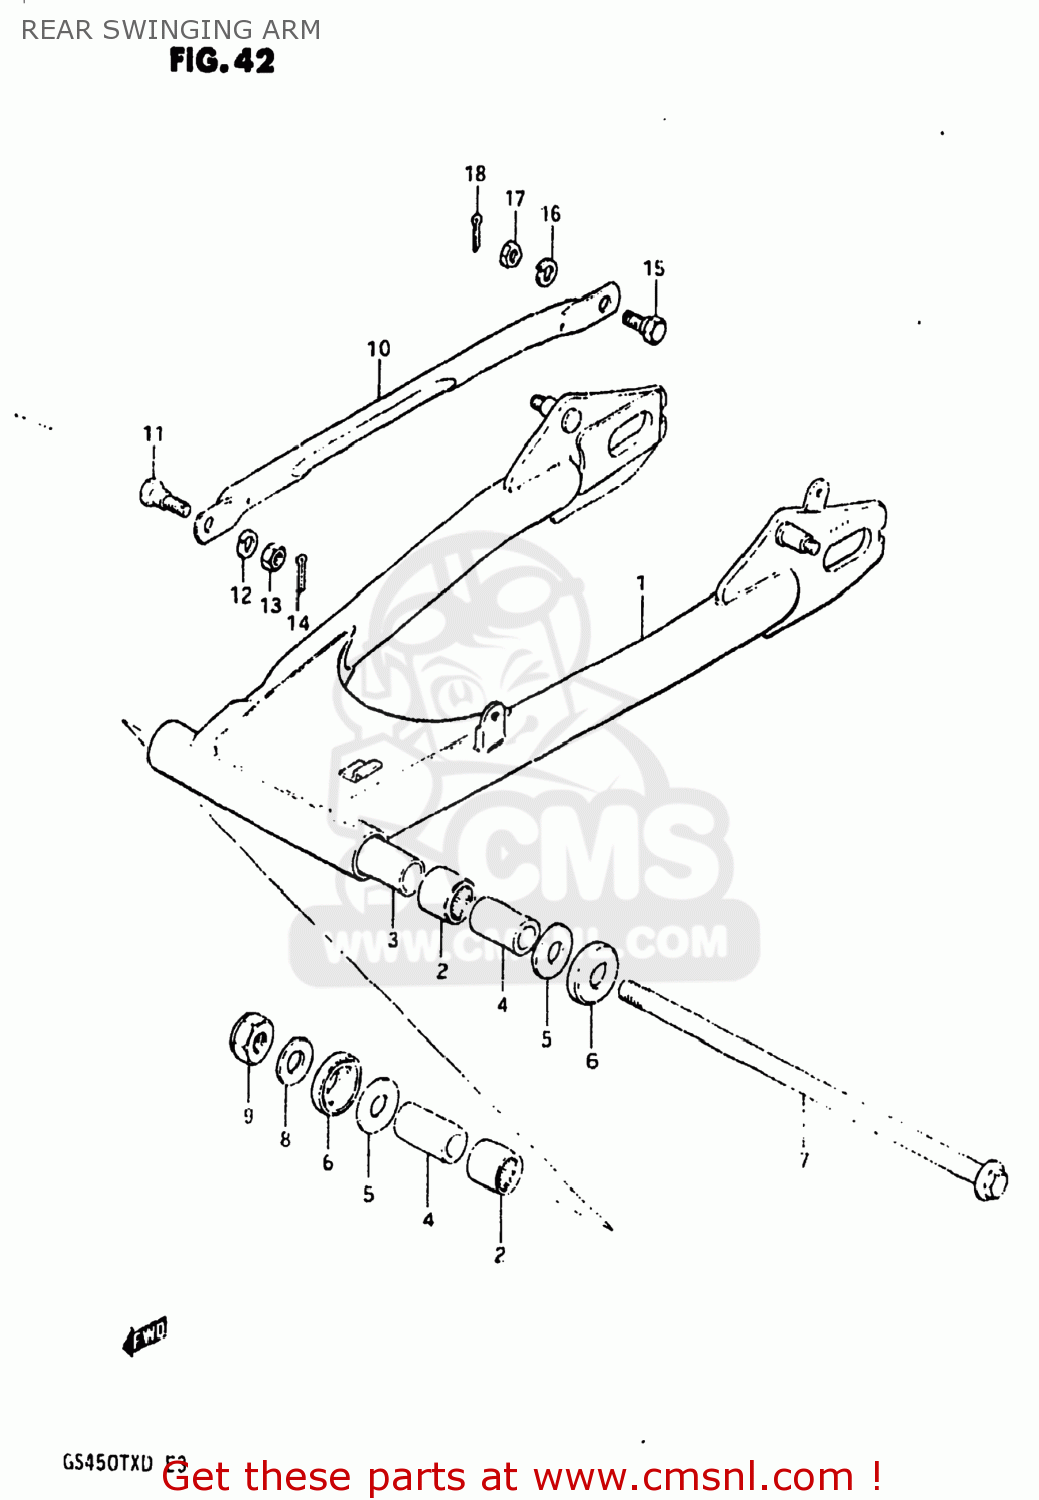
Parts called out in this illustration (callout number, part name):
1	ARM,REAR SWING
2	BEARING(22X29X30)
3	SPACER,SWINGINGARM CTR
4	SPACER,RR SWGARM PIVOT
5	WASHER(14.2X34X1)
6	CVR,RR SWGARM DUST SEAL(OD:40)
7	SHAFT,REAR SWING ARM
8	WASHER
9	NUT 14MM
10	LINK,REAR TORQUE
11	BOLT(10X24.5)
12	LOCK WASHER
13	NUT
14	PIN 20X20
15	BOLT(10X31)
16	LOCK WASHER
17	NUT
18	PIN 20X20
